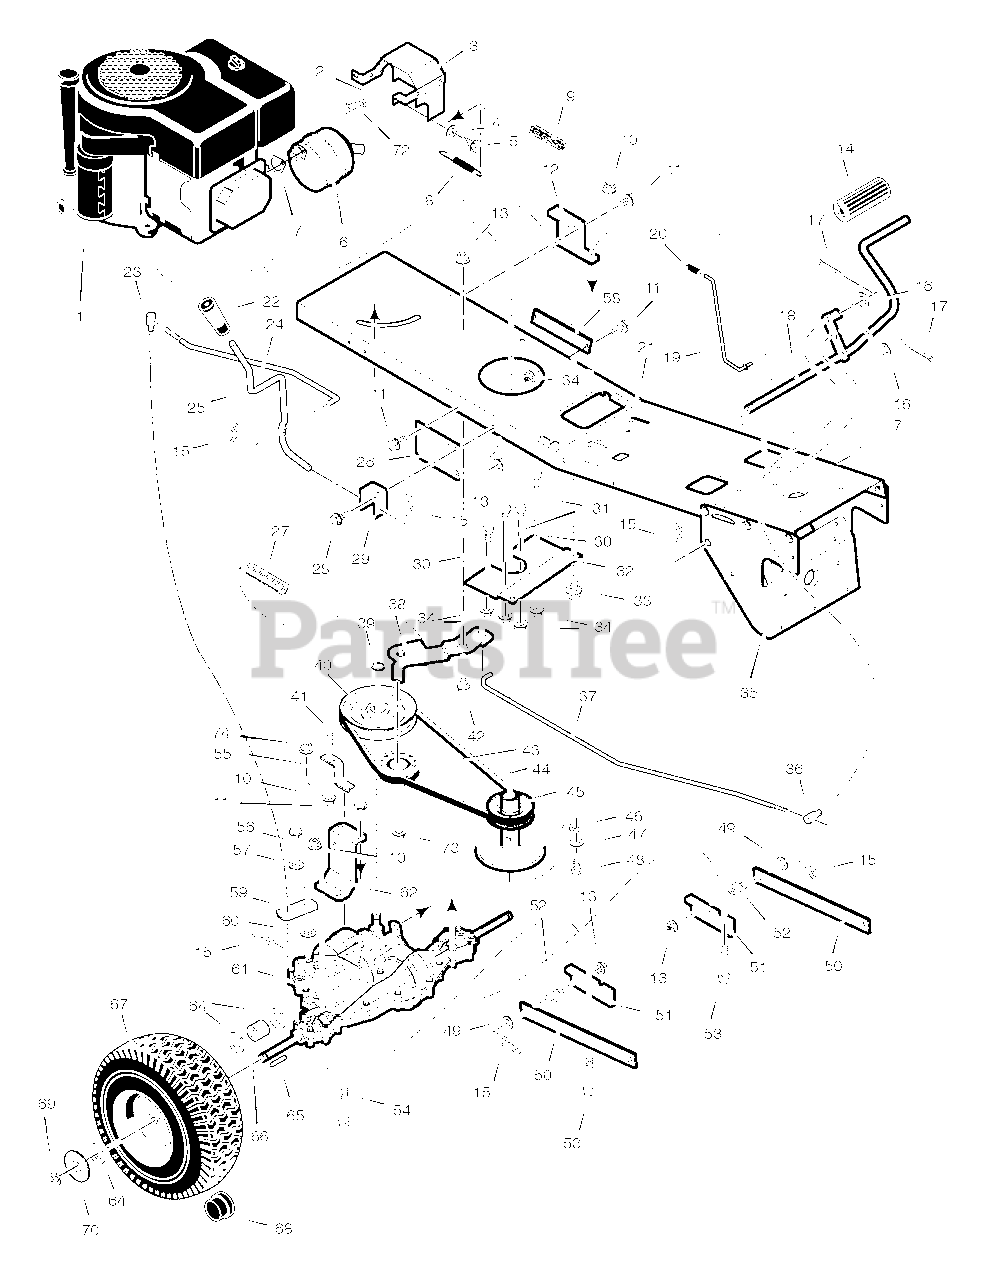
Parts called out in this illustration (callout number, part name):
1	Engine, Briggs & Stratton *
2	Bolt, Hex
3	Shield Assembly, Heat
4	Lockwasher
5	Screw
6	Muffler
7	GASKET, Exhaust
8	Spring, Extension
9	Spring, Extension
10	Nut
12	Bracket, Transaxle -LH
13	Nut, Flange
14	Cover, Pedal
15	Pin, Cotter
16	Washer
17	Pin, Cotter
18	Pedal Assembly
19	Rod, Parking Brake
20	Grip, Parking Brake Rod
22	Grip, Shift Lever
23	Nut, Adjusting
24	Link, Shift
25	Lever, Shift
26	Bracket, Lift Pivot
27	Spring, Extension
28	Bolt, Shoulder
29	Bracket, Pivot
30	Guide, Belt -Short
31	Guide, Belt -Long
32	Plate, Belt Guide
33	Bolt
34	Nut, Flange
35	Bracket, Support
36	Nut, Adjusting
37	Rod, Clutch
38	Clutch Arm Assembly
39	Ring, Retainer
40	Pulley, Drive
41	Bolt, Carriage
42	Bolt, Shoulder
43	Pulley, Idler
44	Belt, Motion Drive
45	Pulley, Split Stack
46	Washer, Star
48	Bolt, Hex
49	Washer
51	Bracket, Rear Hanger
52	Pin, Threaded Shoulder
53	Bolt, Hex
55	Bracket, Torque Reactor
57	Washer, Shift Yoke
58	Plate, Reinforcement
59	Yoke, Shift
61	Transaxle, Peerless **
62	Bracket, Transaxle -RH
65	Key, Square
66	SPACER, Rear Wheel
67	Wheel, Rear -15"
68	Cap, Hub
72	Lock, Screw
73	Nut
74	Nut
